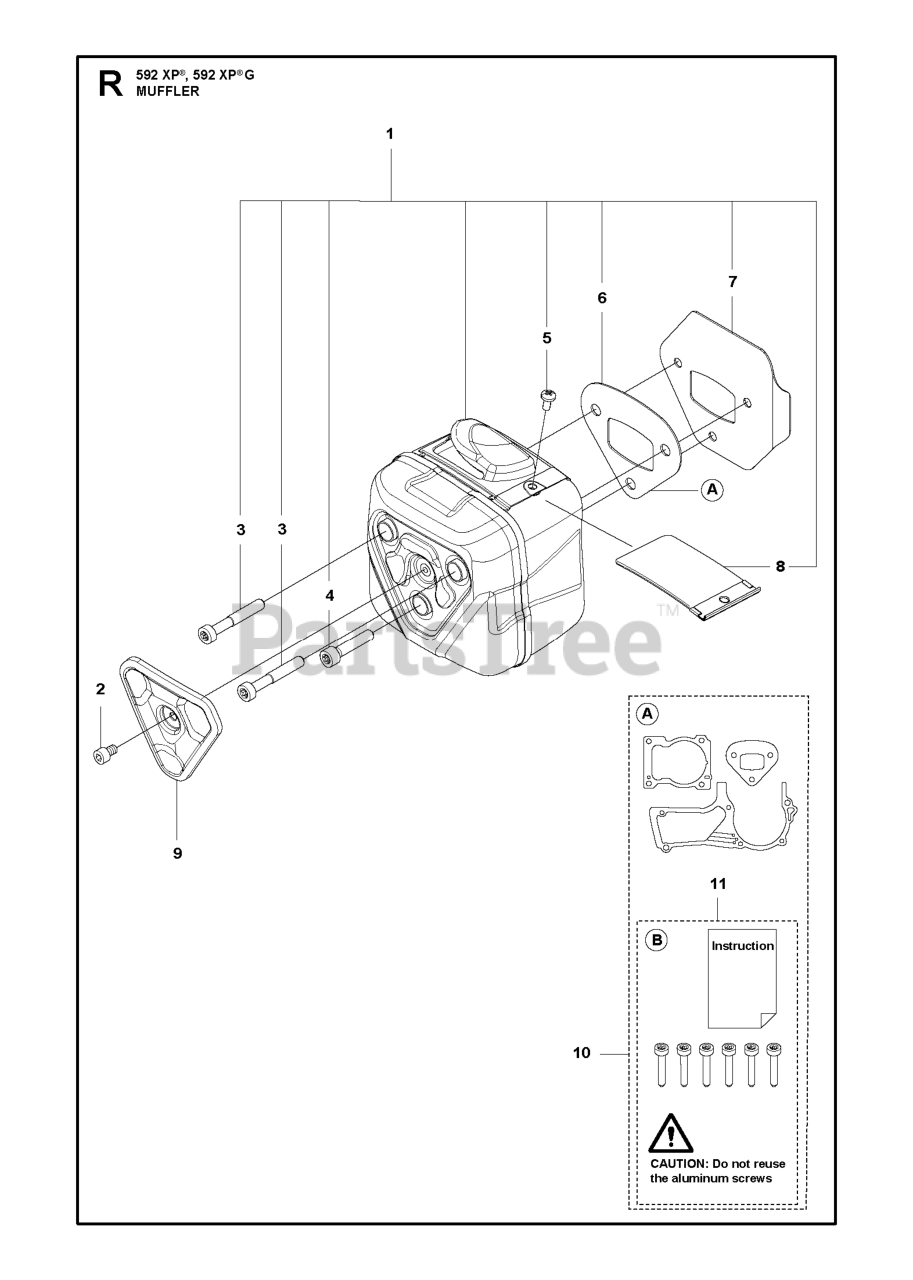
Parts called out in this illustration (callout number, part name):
1	MUFFLER KIT 90CC PRO
2	SCREW ISO 4762 M4X8-A4-80 BUMA
3	SCREW ITXSCM M6X40/25 T27 12.
4	SCREW ISO 14579 M 6 X 30 12.9
6	GASKET 90CC PRO
7	HEAT DEFLECTOR 90CC PRO
8	SPARK ARRESTER 90CC PRO
9	CRASH GUARD 90CC PRO
10	GASKET KIT SPARE PART H592
11	SCREW KIT ALUMINUM 6 PCS
